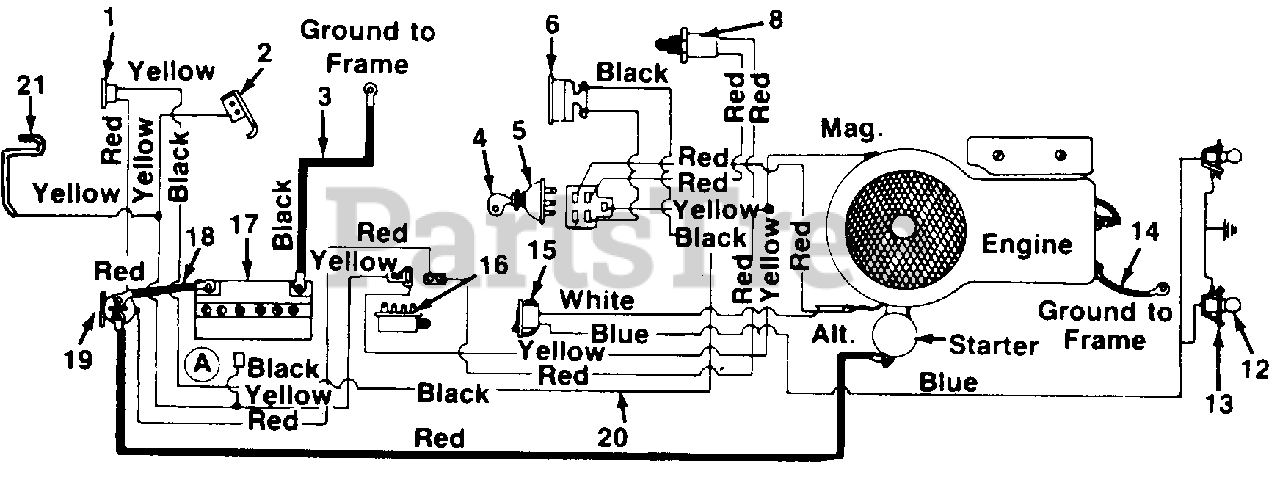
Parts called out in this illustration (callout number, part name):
1	Circuit Breaker
2	Spring-Switch-Reverse
3	Ground Wire 11.5" Lg.
4	Ignition Key
5	Ignition Switch
6	Ammeter
8	Safety Switch
12	Lamp
13	Socket
14	Ground Wire 7.25" Lg.
15	Light Switch
16	Safety Switch
17	Battery
18	Electric Wire 8.0" Lg.
19	Solenoid
20	Wire Harness
21	Spring Switch
